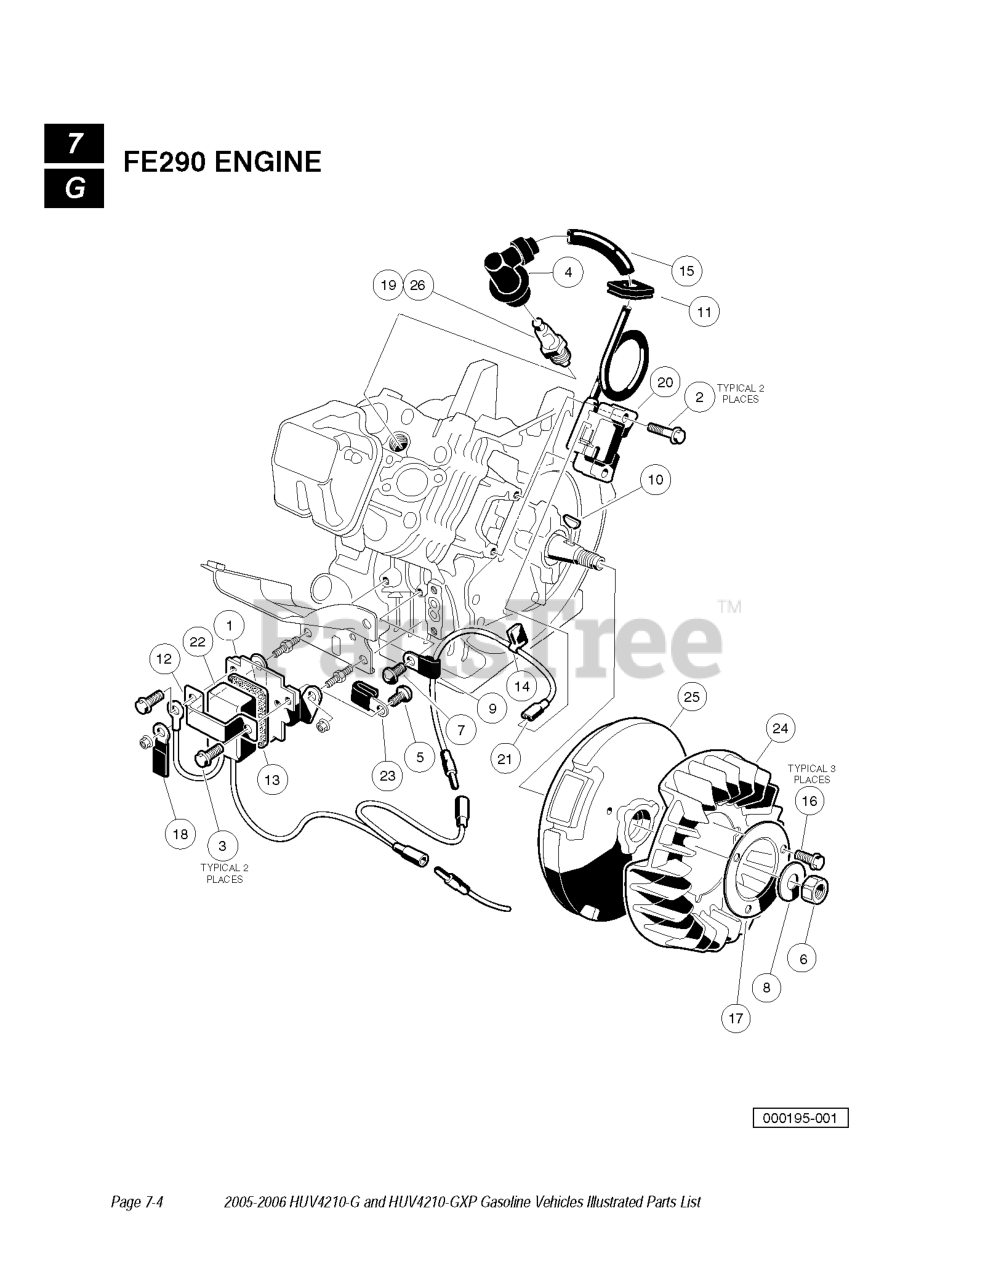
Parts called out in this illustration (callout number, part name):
1	BRACKET, RPM LIMITER
2	BOLT, FLANGED
3	BOLT, FLANGED
4	CAP ASSEMBLY, PLUG
5	SCREW, PAN WP CROSS
6	NUT, HEX, FINE
8	WASHER, M16 FLAT
12	BAND, RPM LIMITER MOUNT
13	DAMPER, RPM LIMITER
15	TUBE, 7MM X 10MM X 70MM
16	BOLT - FLANGED
19	SPARK PLUG OHV
20	COIL, IGNITION
21	LEAD WIRE ASSY
22	LIMITER, RPM
24	FAN, FE290 CW
25	Flywheel, Complete
26	NGK OHV SPARK PLUG
